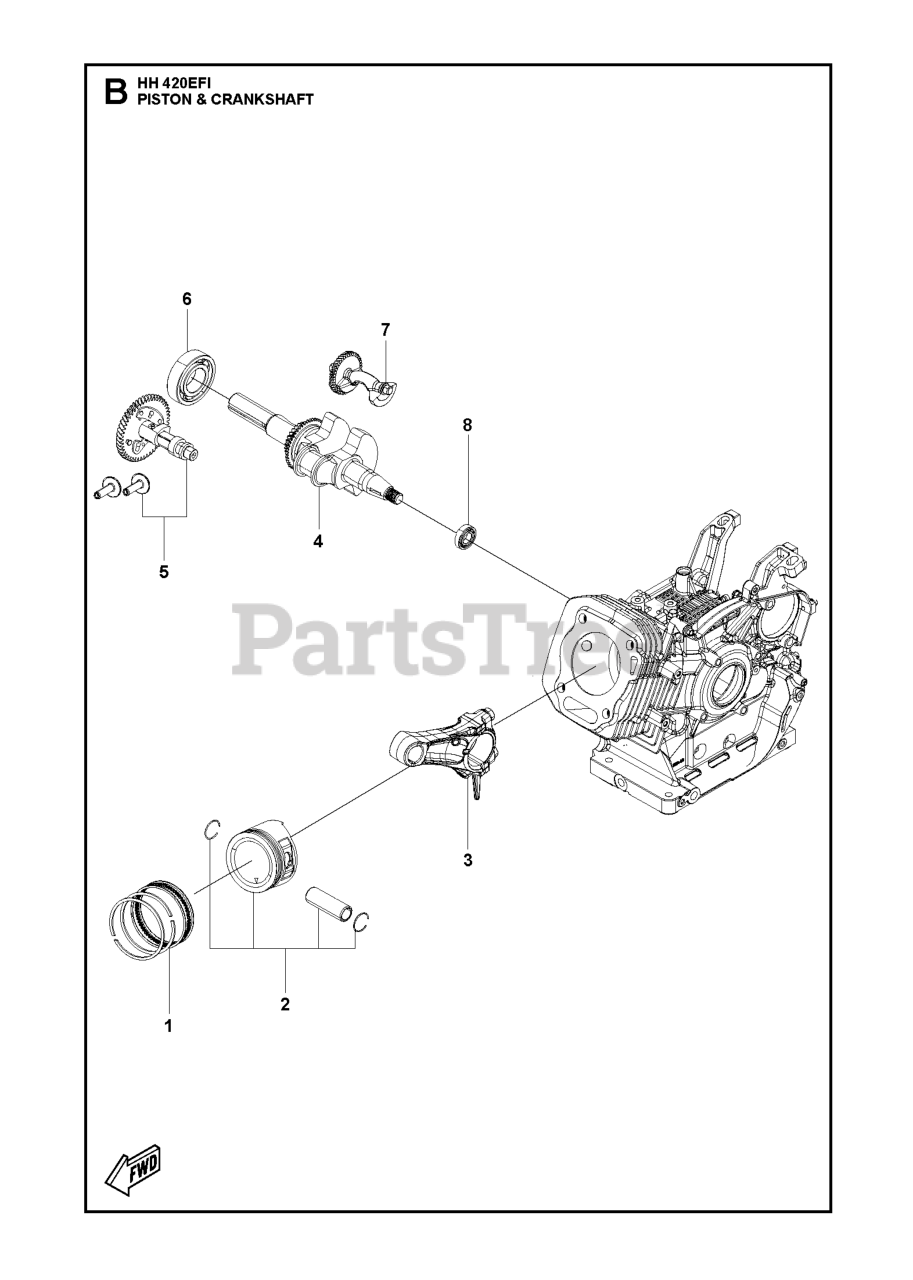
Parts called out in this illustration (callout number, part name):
1	PISTON RING SET
2	PISTON ASSY
3	CONNECTING ROD
4	CRANKSHAFT
5	CAMSHAFT KIT
6	BALL BEARING
7	SHAFT BALANCING SHAFT
8	BALL BEARING
